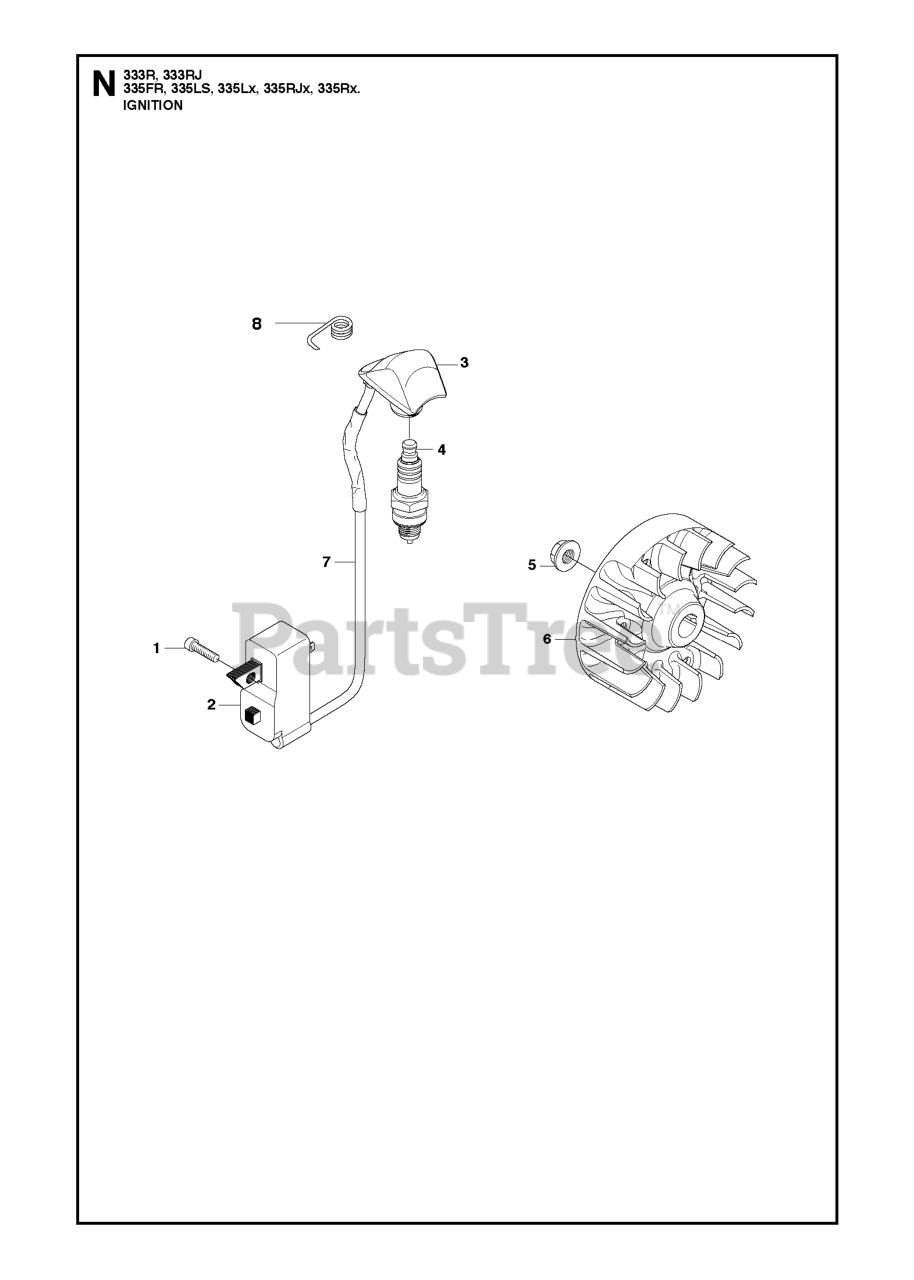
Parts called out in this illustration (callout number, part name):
2	IGNITION MODULE OPS
3	SPARK PLUG CAP
4	SPARK PLUG RCJ6Y NLA
5	FLANGE NUT
6	FLYWHEEL
7	CABLE 13 3/8"IN
